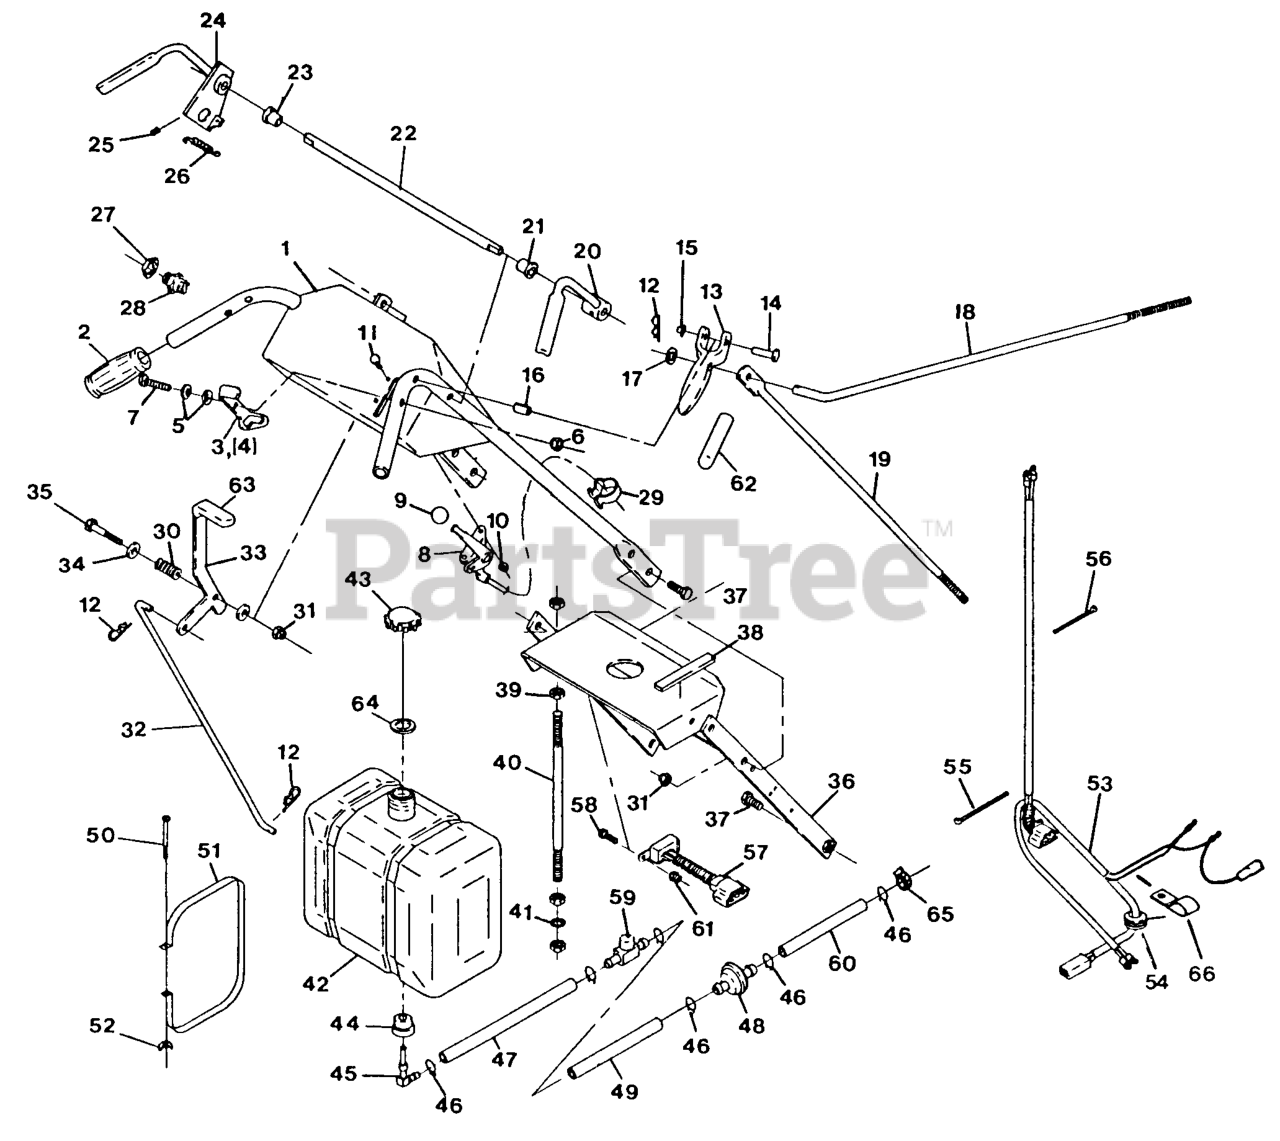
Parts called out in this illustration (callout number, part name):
3	LATCH,W/GRIP RH
4	LATCH,W/GRIP LH
5	WASHER-SPRING
8	CABLE,THROTTLE CONTROL
9	KNOB-BALL
11	BOLT-CARR
12	PIN-COTTER
13	DRIVE LEVER ASM
14	PIN-LEVER, DRIVE
15	NUT-PUSH
16	PIN-ROLL
18	LINKAGE,BRAKE
19	LINKAGE,CALIPER
21	BUSHING-NYLON
22	ROD,CONNECTING
23	BUSHING,FLANGED
25	SCREW-SET
26	SPRING-EXTENSION
28	SWITCH,OPERATOR CNTRL
29	CLIP-CABLE
30	SPRING-COMPRESSION
32	LINKAGE-BLADE, UPPER
38	PAD,PLASTIC TANK
43	CAP-FUEL
45	ELBOW-TANK, FUEL
47	FUEL LINE
50	SCRW,MACH CRPH
52	WINGNUT
54	GROMMET
55	TIE-PLASTIC
56	TIE-CABLE
59	VALVE-FUEL
62	GRIP-LEVER, DRIVE
63	GRIP-LEVER
65	CLAMP-HOSE
